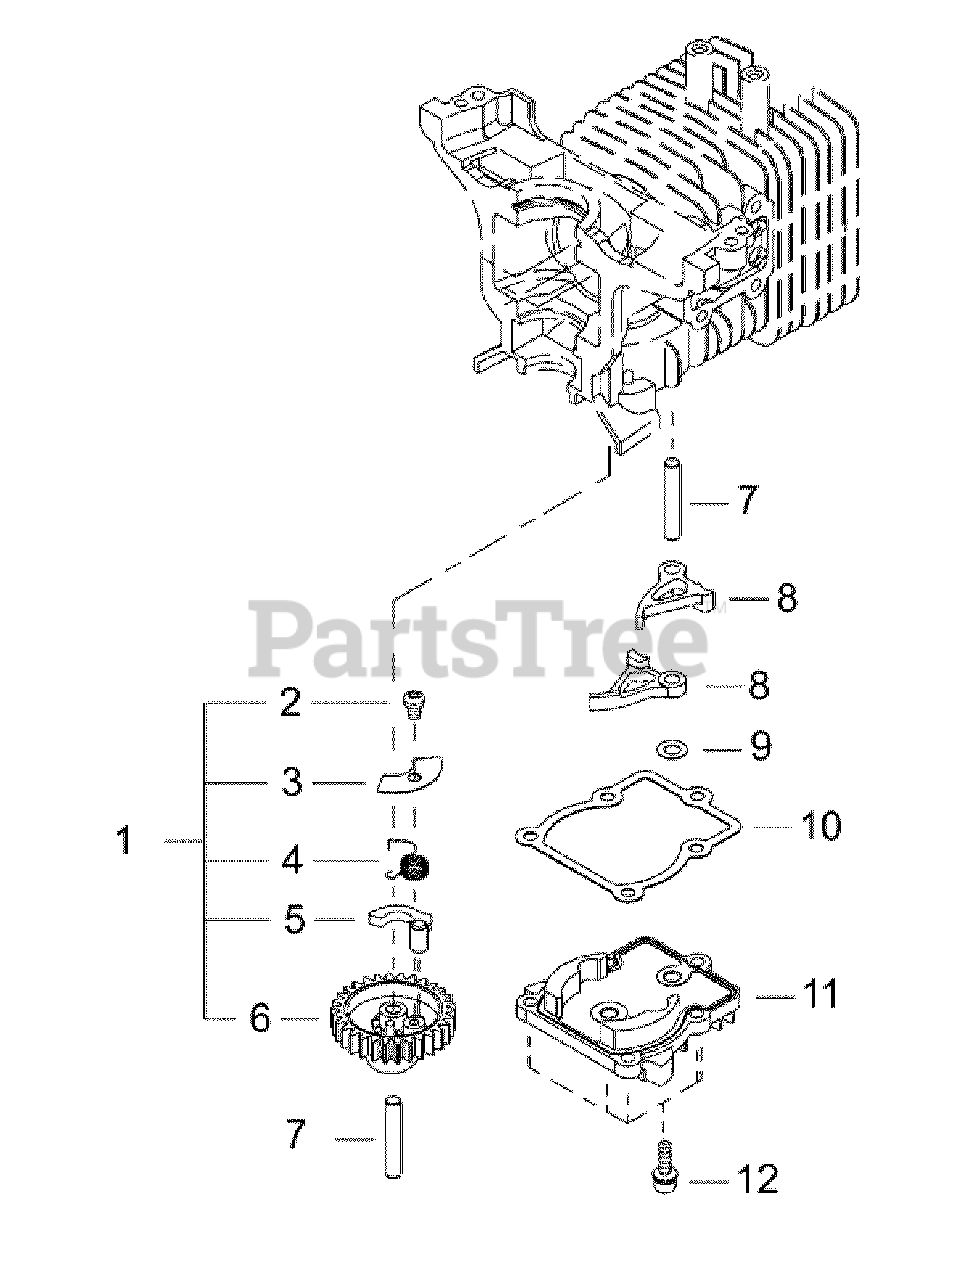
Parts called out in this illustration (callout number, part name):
1	CAM GEAR ASSY
2	SCREW, TAPPING 4×6
3	PLATE, COVER
4	SPRING
5	WEIGHT
6	GEAR, CAM
7	PIN, LOCATING Ø5×29.8 MM
8	FOLLOWER, CAM
9	WASHER 5 MM
10	GASKET, CAM GEAR
11	COVER, CAM GEAR
12	BOLT M4×14
